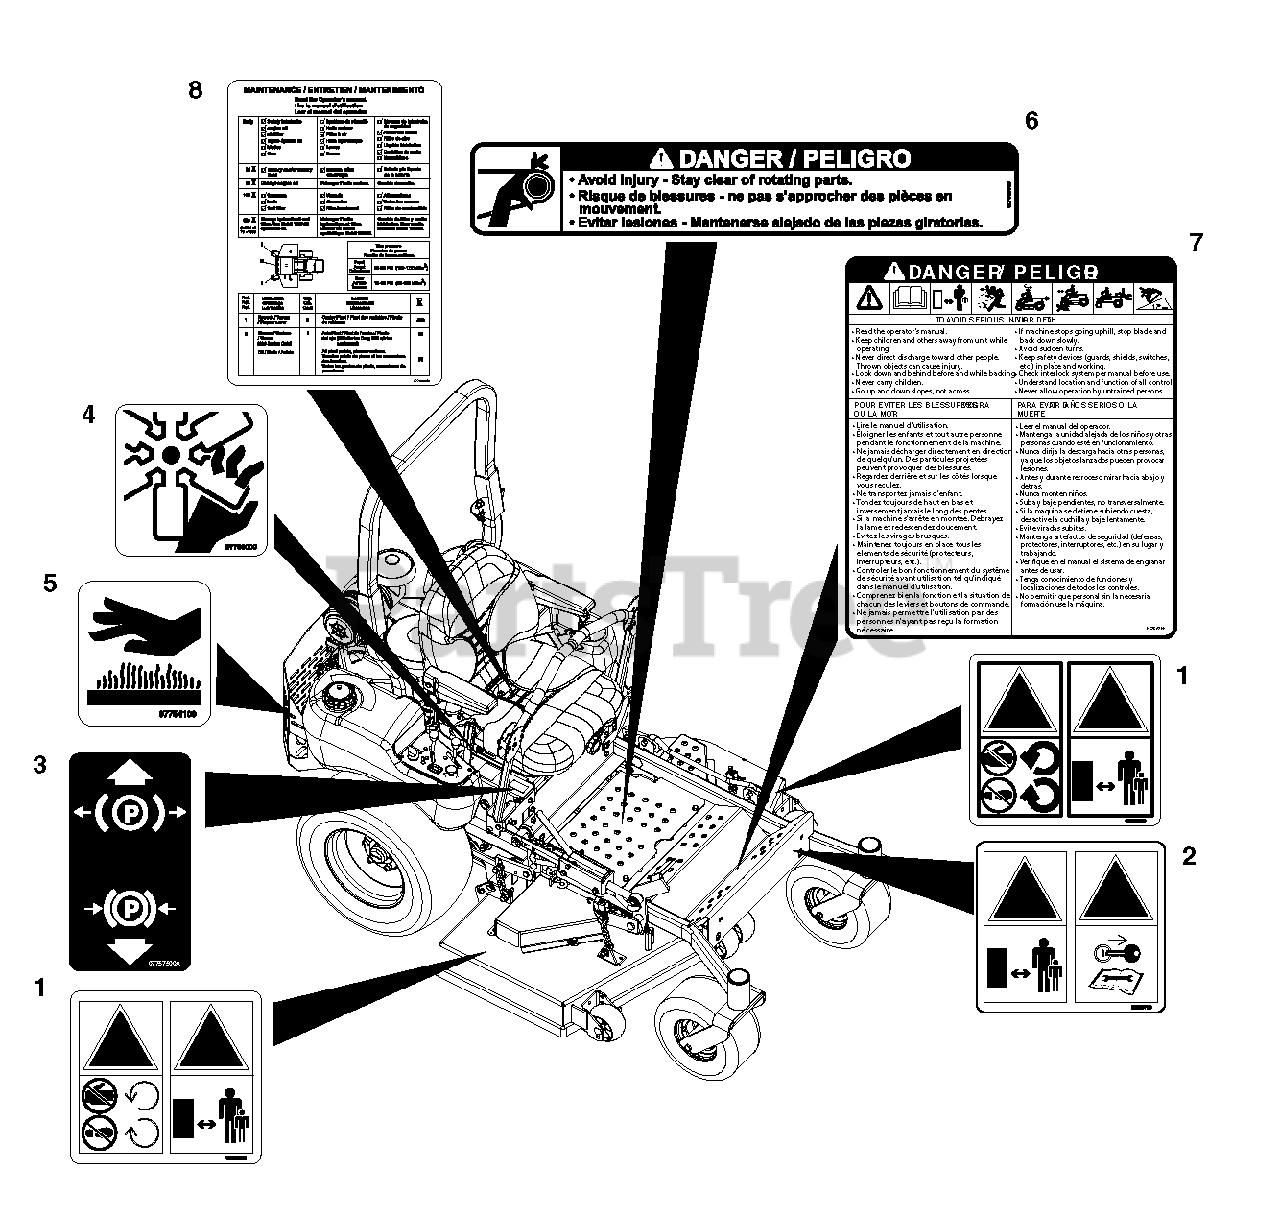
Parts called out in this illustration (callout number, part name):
1	Decal, CE Deck
2	Decal, CE Caution
3	Decal, Parking Brake Lever
4	Decal, Danger Fan
5	Decal, Hot Surface
6	Decal, Danger Rotating Parts
7	Decal, Danger- Bilingual
8	Decal, Maintenance Instructions
